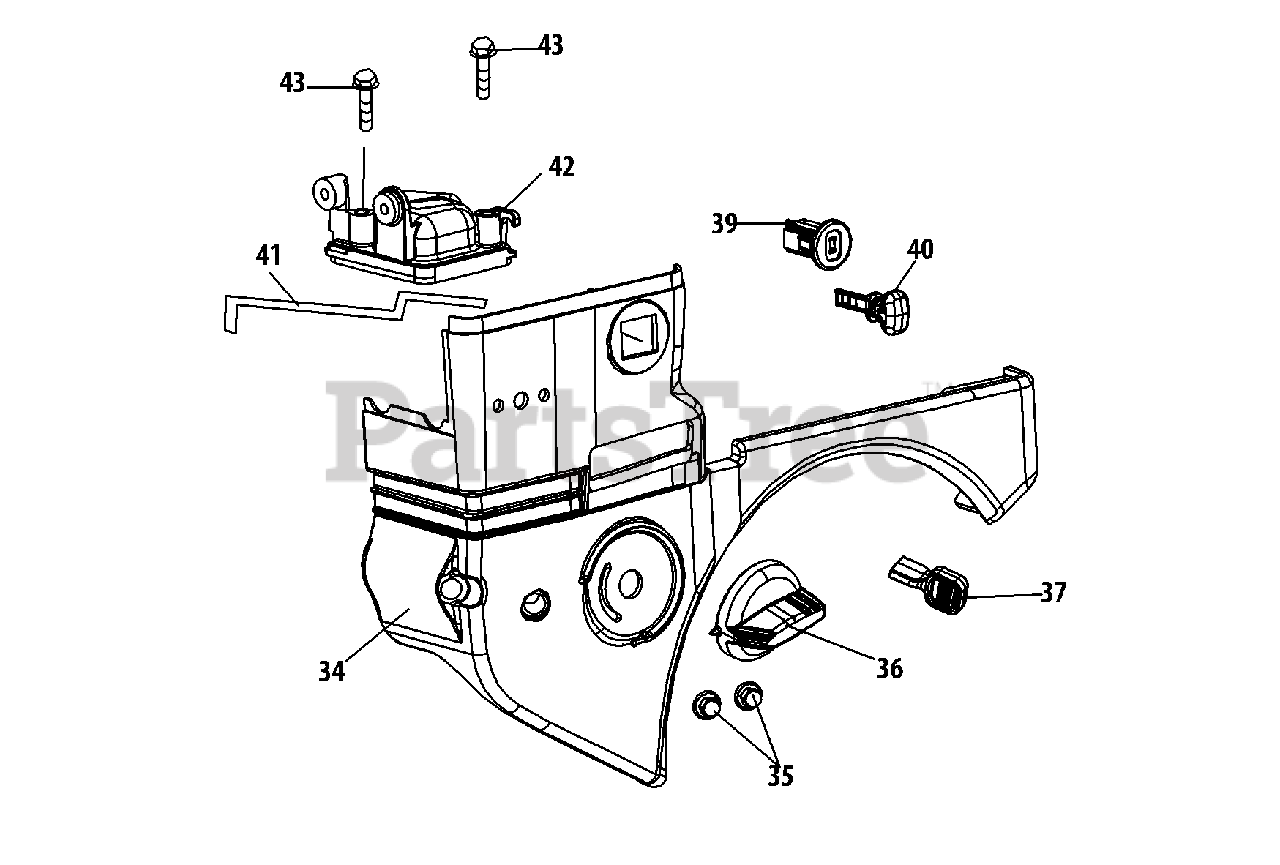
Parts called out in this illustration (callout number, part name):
34	Air Cleaner Housing
36	Choke Knob
37	Throttle Control Knob
39	Engine Switch Base
40	Key
41	Choke Linkage
42	Heater Box
43	Bolt M6×28
